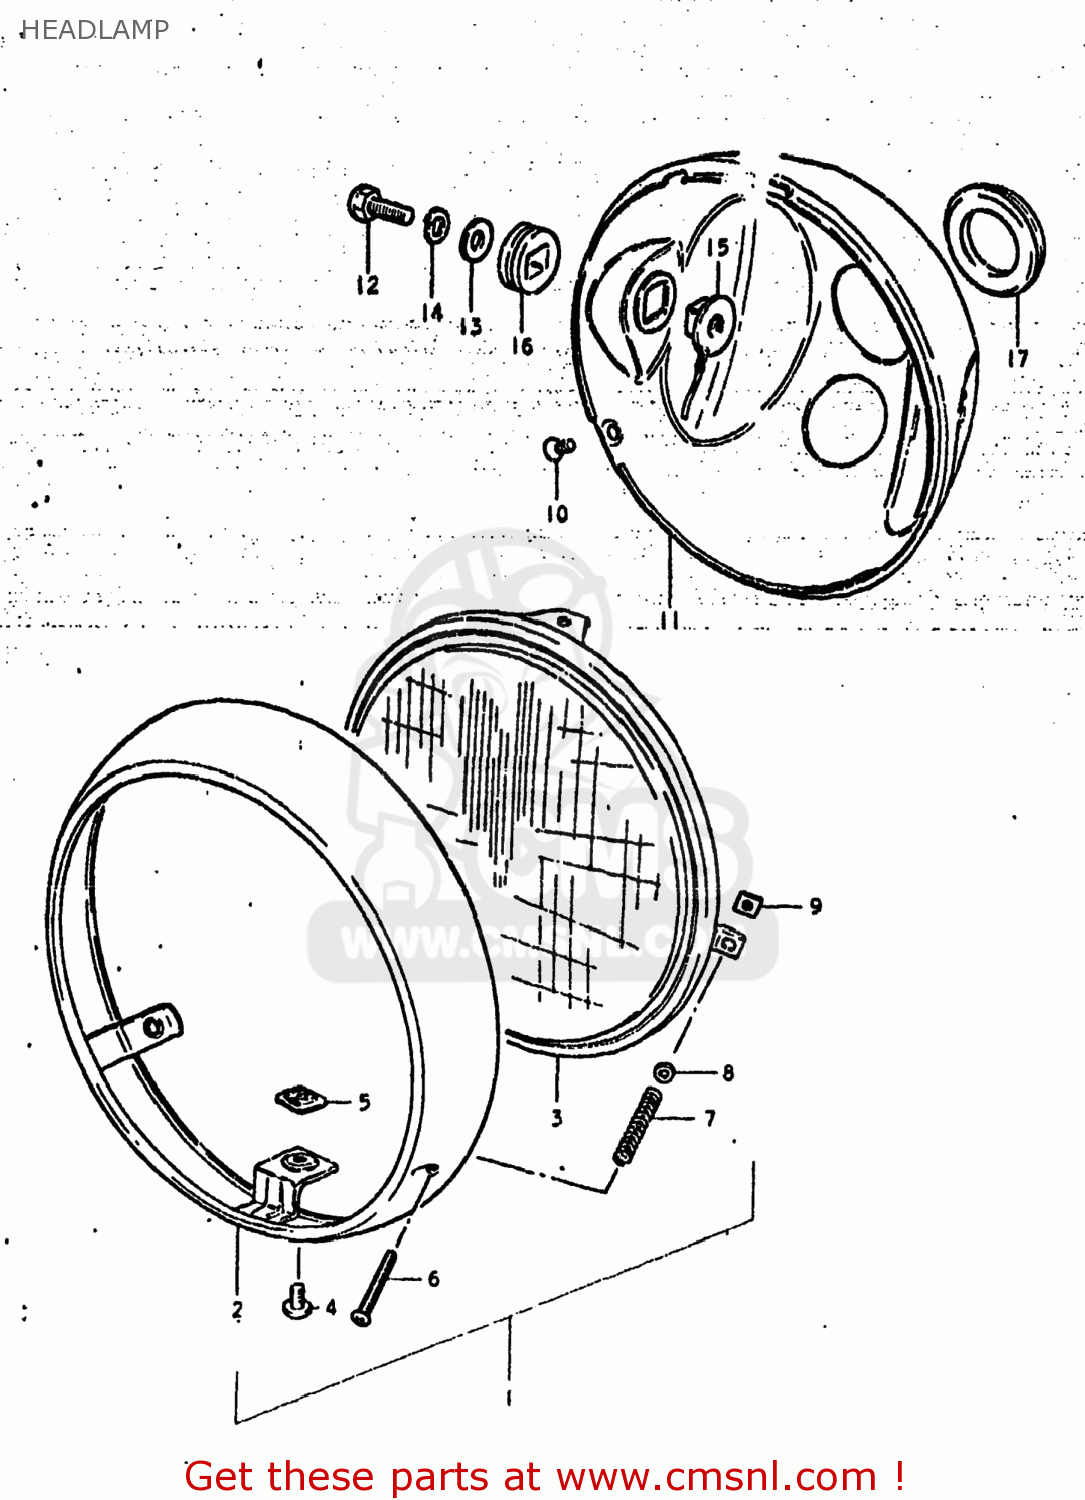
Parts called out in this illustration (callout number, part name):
1	HEADLAMP ASSEMBLY
2	RIM,HEADLAMP
3	LAMP UNIT
4	SCREW
5	NUT
6	SCREW,HEADLAMP ADJUST
7	SPRING,HEADLAMP ADJUST
8	WASHER
9	NUT,HEADLAMP ADJUSTER
10	SCREW
11	HOUSING,HEADLAMP
12	BOLT
13	WASHER
14	LOCK WASHER
15	SPACER,HEADLAMP HOUSING
16	CUSHION,HEADLAMP HOUSING
17	GROMMET,HEADLAMP HOUSING
